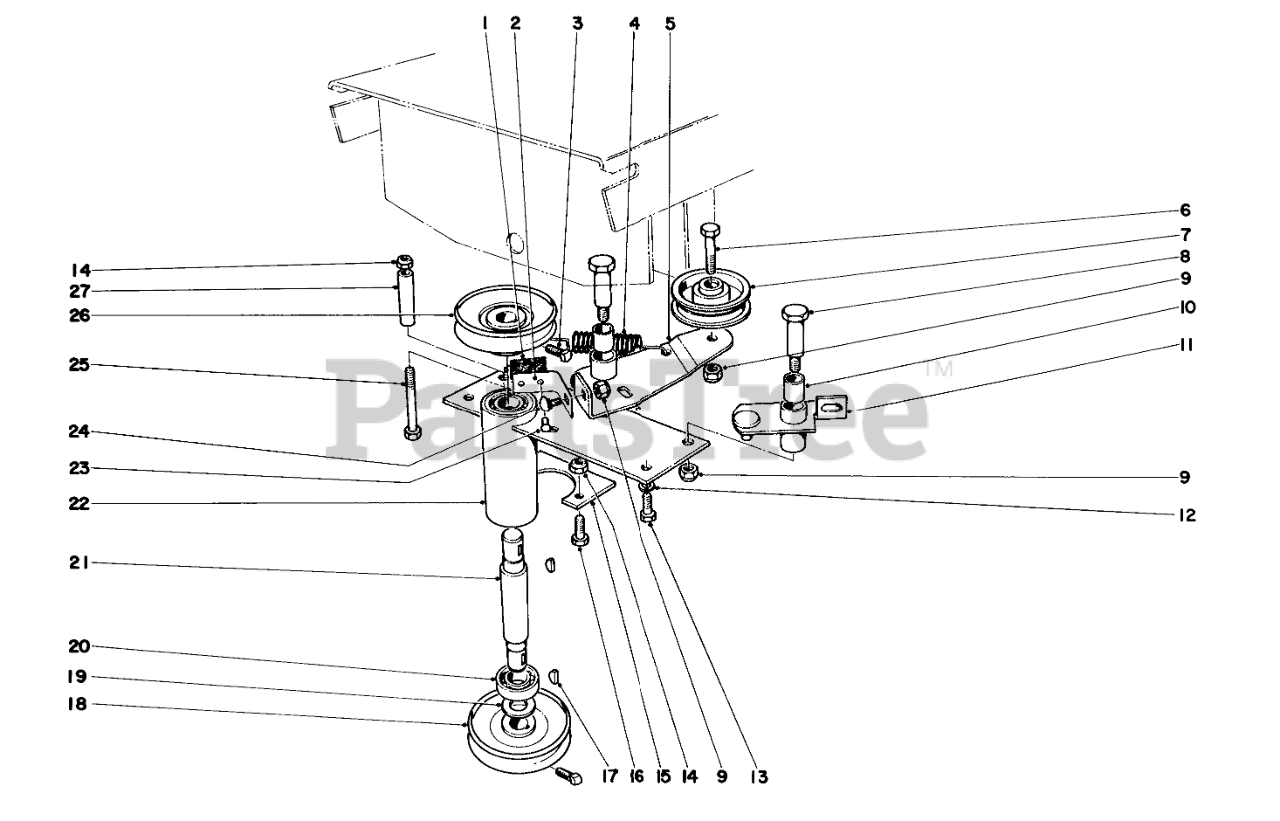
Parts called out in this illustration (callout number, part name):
1	BLADE BRAKE LINING
2	Brake Spring
3	5/16-18 X 1/2 SQ HD
4	Spring
5	Idler Plate
6	SCREW-HH
7	PULLEY-IDLER
8	Axle Bolt
9	NUT-LOCK, CONE
10	BUSHING
11	Pivot Bracket (Incl. Ref. #10)
12	WASHER-LOCK
13	SCREW-HH
14	NUT-LOCK, CONE
15	Retainer P.T.0. Tube
16	SCREW-HH
17	KEY-WOODRUFF
18	Pulley
19	Bearing Washer
20	Bearing
21	Shaft
22	P.T.0. Tube
23	Rivet
24	SCREW-CARR
25	SCREW-HH
26	Pulley
27	Spacer
